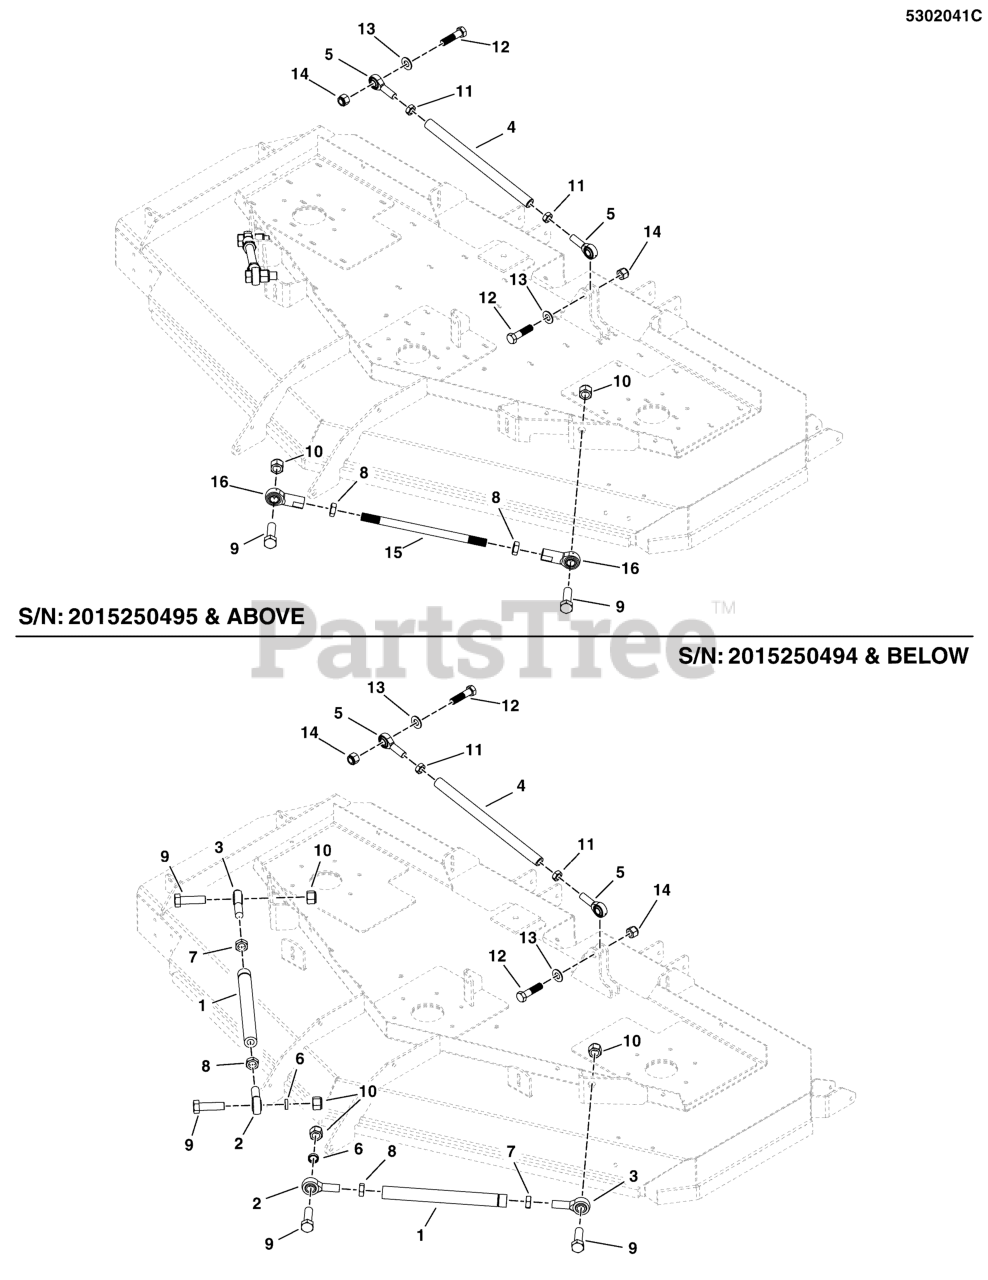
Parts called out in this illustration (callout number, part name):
1	ROD, DECK STABILIZER, 12.31 LG ECOAT
2	BALL JOINT, 3/4-16, MALE
3	BALL JOINT, 3/4-16 MALE, LH
4	SHAFT, DECK STABILIZER, 14.50, CZ
5	BALL JOINT, 5/8-18, MALE
6	SPACER, .76 X 1.00 X .25
7	NUT, 3/4-16 HEX JAM, LH
8	NUT, 3/4-16 HEX JAM
9	BOLT, 3/4-16 X 2-1/2 YZ GD5
10	NUT, 3/4-16 HEX NYLON LOCK
11	NUT, 5/8-18, HEX JAM
12	BOLT, 5/8-11 X 2-1/2 GD5, CZ
13	WASHER, 5/8 SAE
14	NUT,5/8-11 HEX NYLON LOCK
15	ROD, 3/4-16 X 12.31
16	BALL JOINT, 3/4-16, FEMALE
